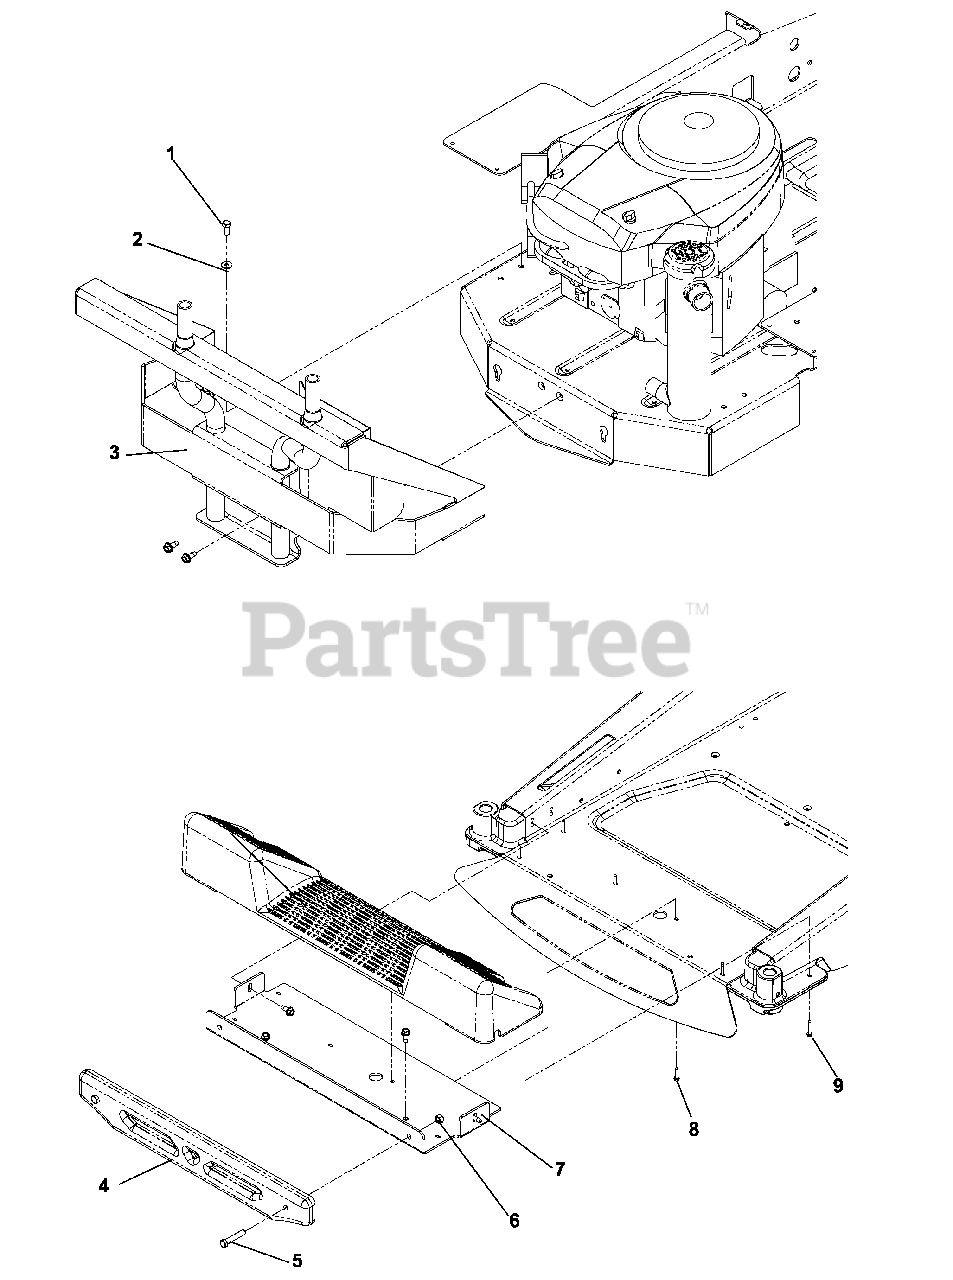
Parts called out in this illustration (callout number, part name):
1	Washer, 1/4
2	HCS, 5/16-18 x 3/4, Gr8
3	Rear Collection Hitch
4	Weight, Cast
5	HCS, 3/8-16 x 2, Gr5
6	Nut, 3/8-16, nyloc
7	Weight bracket
8	Screw, #10-12 x 1, wash hd
9	Screw, #10-12 x 1 1/4, wash hd
